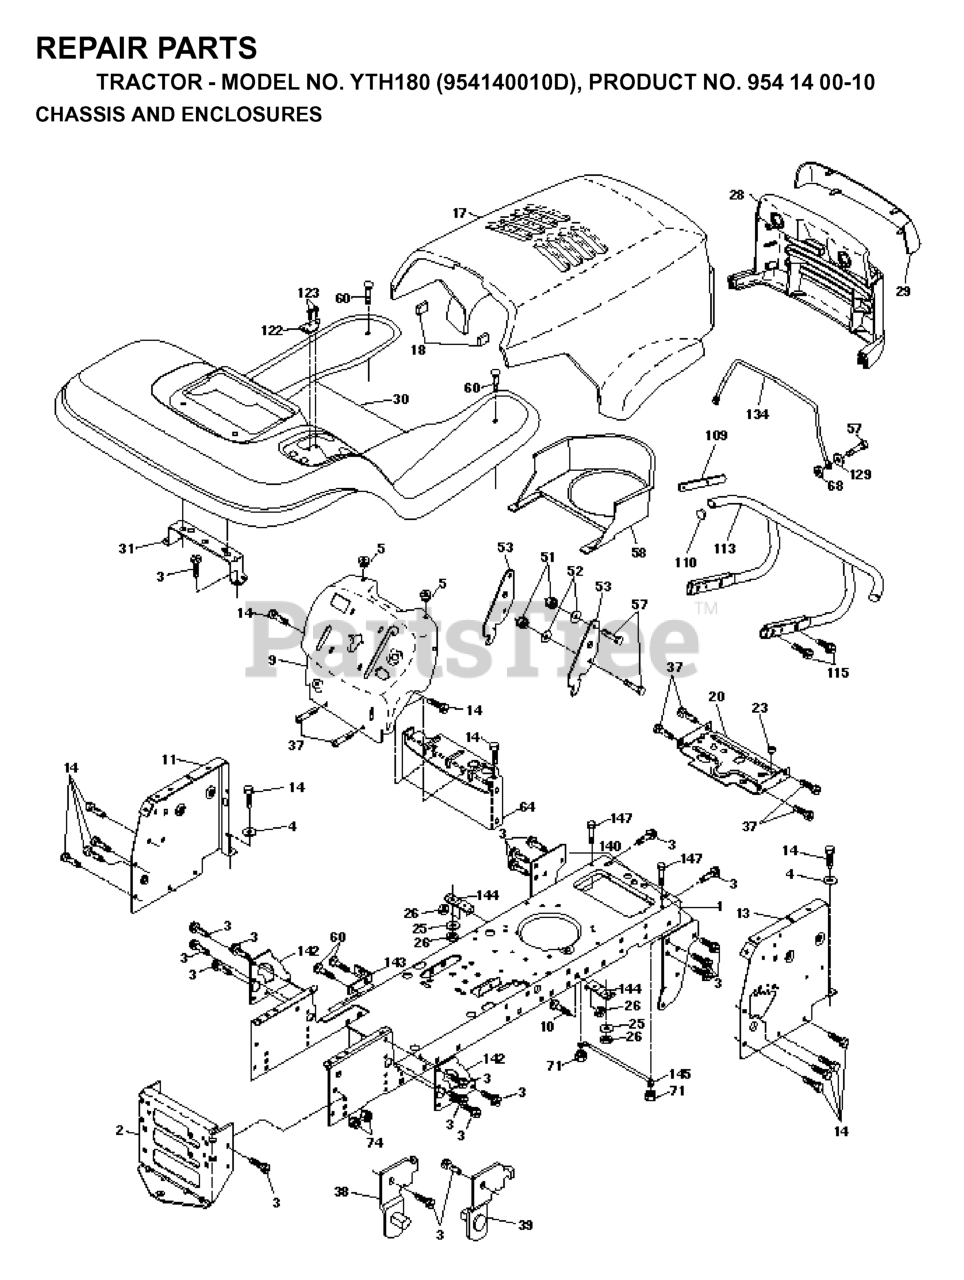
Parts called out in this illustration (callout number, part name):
1	CHASSIS WELDMENT
2	STRETCH DRAWBAR
3	SCREW
4	Washer 13/32 X 3/4 X 16 Ga.
5	BUMPER.RUBBER.HOOD
9	DASH PANEL
10	BOLT D
11	PANEL DASH LH
17	HOOD - LT/YT
18	BUMPER HOOD T
20	PLATE MTG
23	BUSHING.SNAP.NYL.BLK.
25	WASHER
26	NUT
28	GRILLE LT/PL HUSQVARNA
29	LENS LT/PL HUSQVARNA
30	FENDER FOOTREST
31	BRACKET.SUPPORT.FENDER
37	Screw 5/16-18 x 1/2 Hex, Self Tapping 5/16-18 x 1/2
38	BRACKET LH PIVOT
39	BRACKET RH PIVOT
51	LOCKNUT.NYLOC.1/4-20
53	BRACKET PNT PICK OFF LT/PL
57	BOLT
60	Bolt - Rd. Hd. Sq. Neckiage 3/8 16 x 3/4
64	DASH LOWER
68	NUT
71	NUT.CROWNLOCK.1/4
109	BRACKET BUMPER
110	PLUG PLASTIC
111	Bolt, Carriage 3/8-16 UNC x 1-1/2
112	WASHER
122	BRACKET SHIFT STLT
123	SCREW.TT.#10-32X.5.3/8.FLANGE
134	ROD SUPPORT HOOD LT/PL HUS.
140	BRACKET SUSPENSION FRONT
142	PLATE REINFORCEMENT
143	BRACKET, SWAY BAR
144	BRACKET FOOTREST
145	ROD PIVOT CHASSIS/HOOD
146	SCREW TORX HD 5/16X18
147	BOLT.HEX.1/4.X.3/4.DICHROMATE
